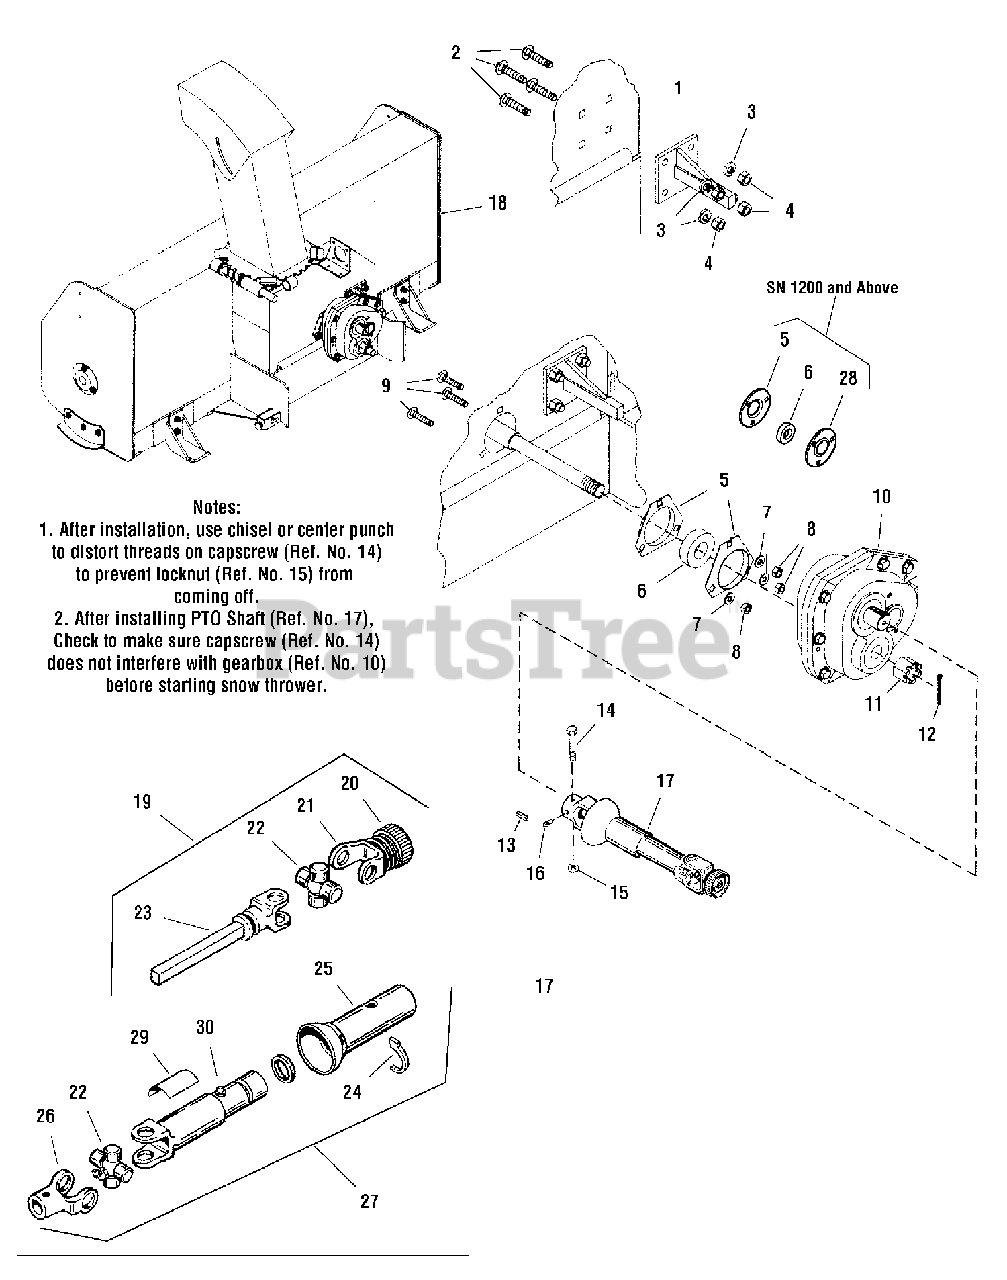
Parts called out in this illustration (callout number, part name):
1	PLATE & BAR ASSEMBLY
2	CARRIAGE BOLT, 3/8-16 x 1
3	LOCKWASHER, 3/8
4	NUT, Hex, 3/8-16
5	FLANGE, Bearing 3-hole, (SN 1 to 1120)
5	FLANGE, Bearing, (SN 1200 and above)
6	BEARING, (SN 1 to 1120)
6	BEARING, Cartridge
7	LOCKWASHER, 5/16
8	NUT, Hex, 5/16-18
9	CARRIAGE BOLT, 5/16-18 x 5/8
10	GEARBOX ASSEMBLY (See Gearbox group), Use 30 Weight Engine Oil.
11	NUT, Slotted Hex, 3/4 -16, L.H.
12	PIN, Cotter
14	CAPSCREW, Hex Head, 1/4-20 x 1-7/8
15	LOCKNUT, Hex,1/4-20
16	SET SCREW, 5/16 -18 x 3/8, G8
17	DRIVE SHAFT, PTO
18	BLOWER HOUSING(S/N 1 to1120)
18	BLOWER HOUSING, (S/N 1200 and Above)
19	JOINT & SHAFT ASSEMBLY, w/guard (Incl Ref. Nos. 20-23)
20	SPRING LOCK ASSEMBLY
21	YOKE ASSEMBLY, Spring-Lock
22	CROSS & BEARING KIT
23	YOKE & SHAFT ASSEMBLY
24	REPAIR KIT, Nylon
25	GUARD, Outer
27	JOINT & TUBE ASSEMBLY, w/guard (lncl. Ref. Nos. 22, 24-26, 29-30)
28	FLANGE W/ GREASE FITTING, (SN 1200 and above)
29	DECAL, Warning, Drive Shaft
30	YOKE, TUBE & SLIP SLEEVE
